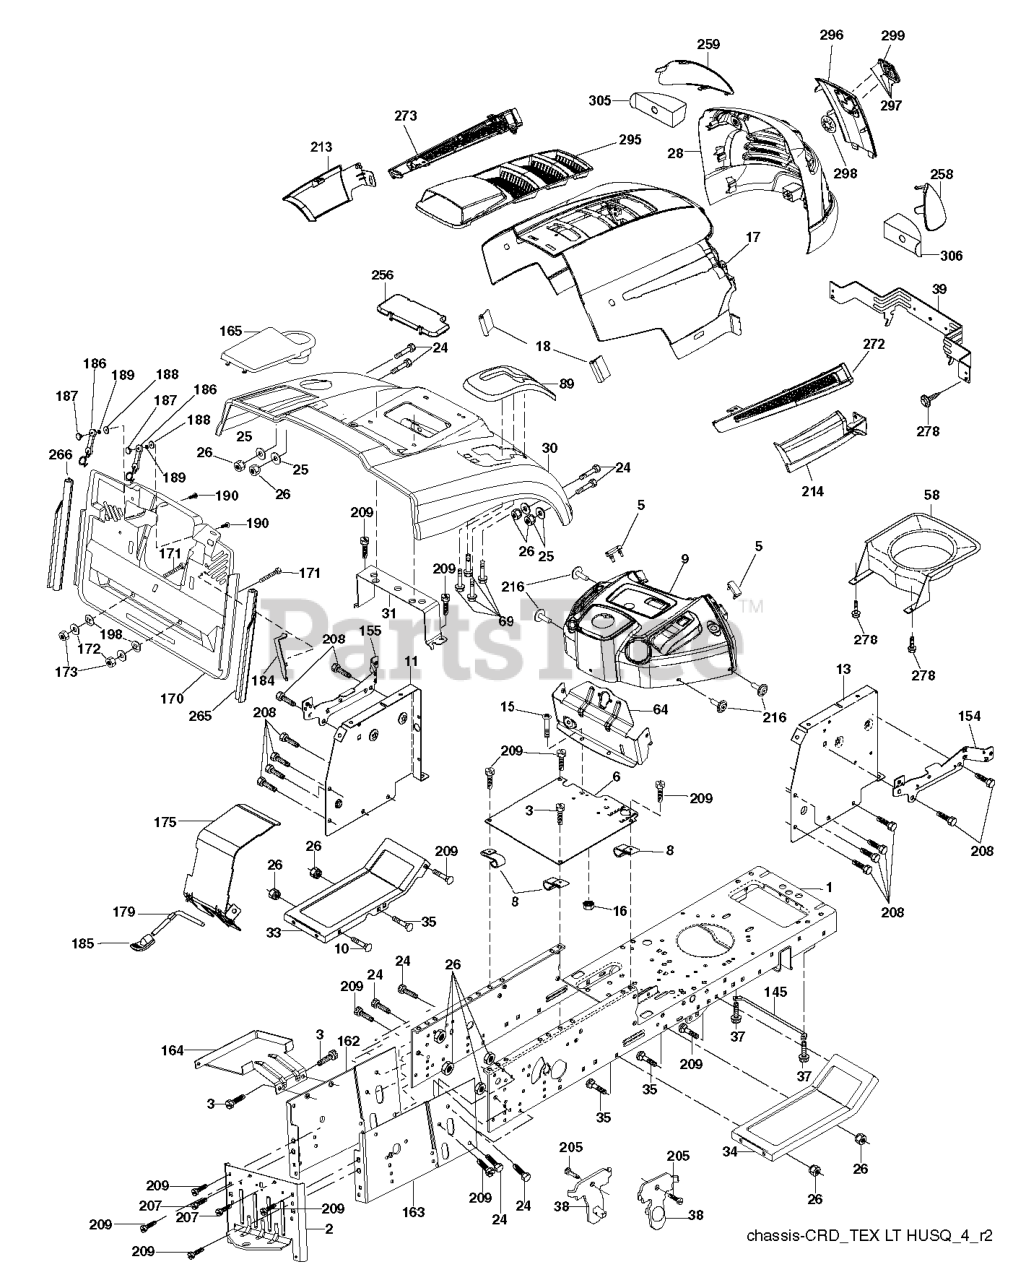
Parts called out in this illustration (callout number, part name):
2	DRAWBAR
3	SCREW 3/8-16X3/4
5	SCREW.#10 X 0.750.BOS
6	PLATE
8	CLIP,INSULATOR
10	BOLT D
11	PANEL.DASH.LH.LTX
13	PANEL ASM, DASH RH
15	Screw, Machine, Truss Head 5/16-18 UNC x 3/4
16	NUT
17	HOOD.HUSQVARNA.LT.ORANGE
18	BUMPER.HOOD.TEX.HUSQVARNA
25	WASHER
26	NUT
28	GRILLE.SVC.HUSQVARNA.LT.GREY
30	CONSOLE.CRD.AUTO.GRY
31	BRACKET SUPPORT FENDER
33	FOOTREST PNT LH
34	FOOTREST PNT RH
37	Screw 5/16-18 x 1/2 Hex, Self Tapping 5/16-18 x 1/2
38	BRACKET ASM PIVOT MOWER REAR
39	BRACKET PIVOT
69	SCREW.HI-LO.CONSOLE
89	CONSOLE.CRD.AUTO.GREY.2005
145	ROD.PIVOT.HOOD
162	BRACKET
163	BRACKET EXTEN CHASSIS RH CRD
165	RP.COVER.BATTERY.CRD.GREY
172	WASHER
175	DOOR TRAP
179	ROD PIVOT FBI
184	BRACKET.ACTUATOR.BAGGER.SRD
186	LATCH ASSY
187	WELDNUT
189	LOCKWASHER #10
190	SCREW
207	SCREW, 5/16-18 X 1/2
208	SCREW 3/8-16X1/2
209	SCREW, 3/8-16X3/4
213	SKIRT SIDE LH
214	SKIRT SIDE RH
216	SCREW HEXWSHR 1/4-20X3/4
256	COVER FENDER CRD
258	LENS.HUSQVARNA LT.RH
259	LENS.HUSQVARNA LT.LH
265	SEALING
266	SEALING
272	VENT SIDE HOOD LH
273	VENT SIDE HOOD RH
278	SCREW.#10 X 0.750.BOS
295	VENT TOP HOOD
296	TRIM
297	CLIP.RETAINER.TINNER.
298	NUT PUSH M
299	RP LOGO
305	INSERT REFLECTIVE
306	INSERT.REFLECTIVE.RH.
